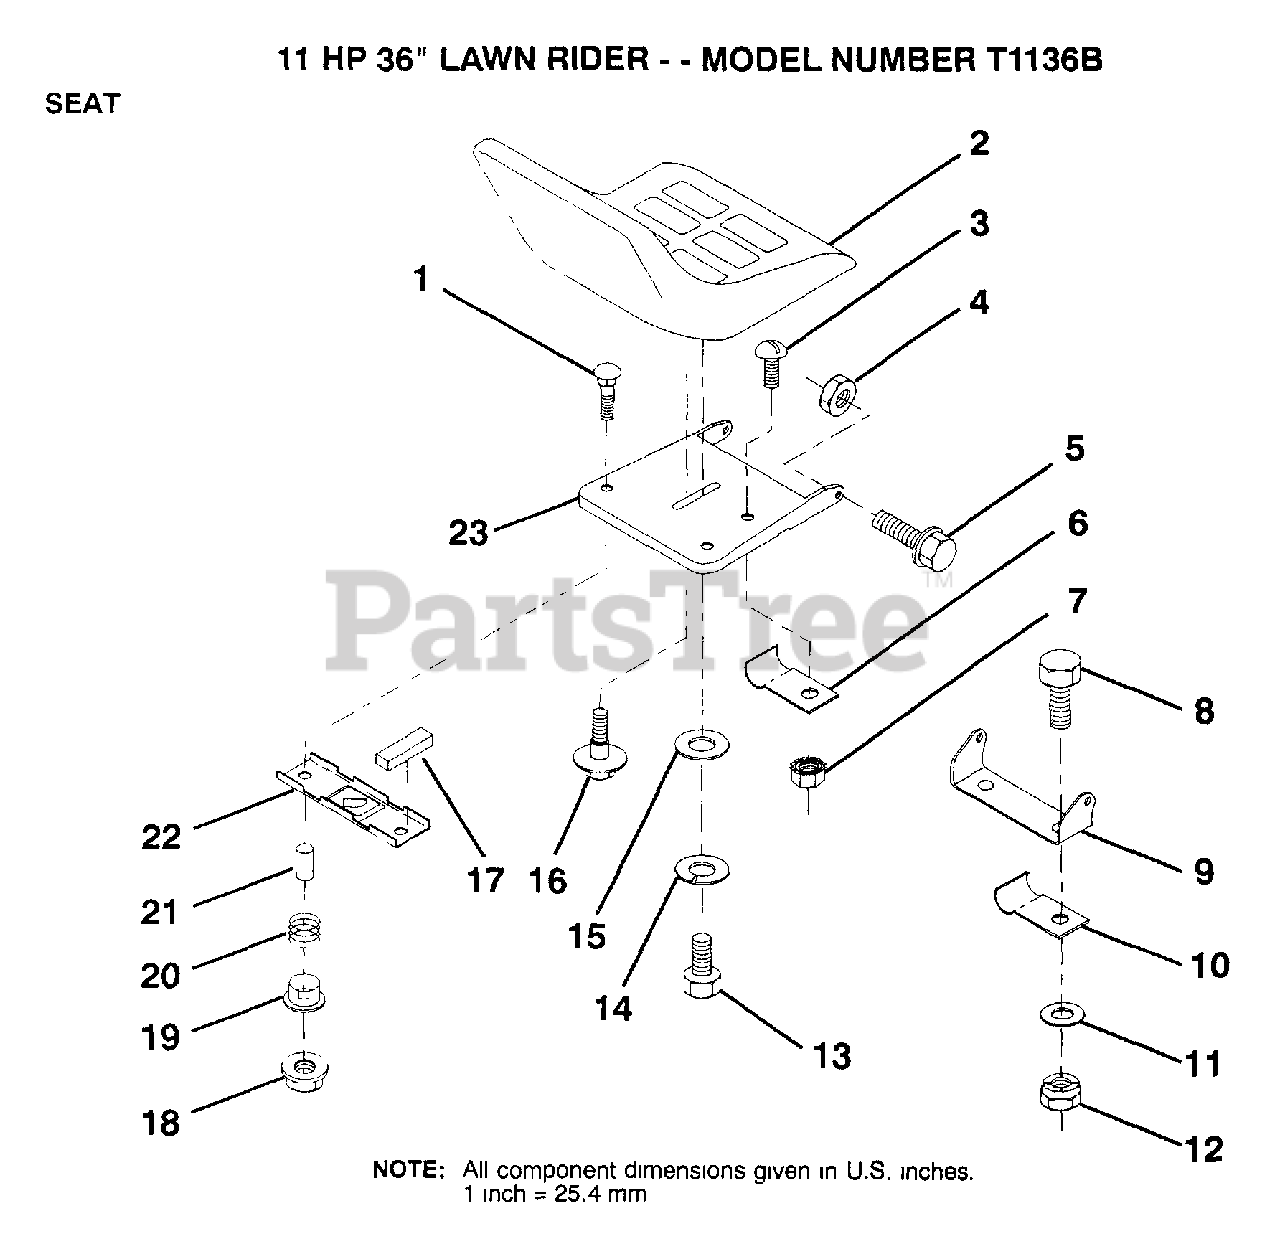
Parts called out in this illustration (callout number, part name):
7	"NUT,KEPS"
10	"CLIP,INSULATOR"
11	WASHER
13	BOLT
14	LOCKWASHER
15	WASHER
16	"BOLT,SHOULDER"
17	STRIP FORM
19	BUSHING
20	SPRING
21	SPACER SPLIT
22	BRKT SWITCH
